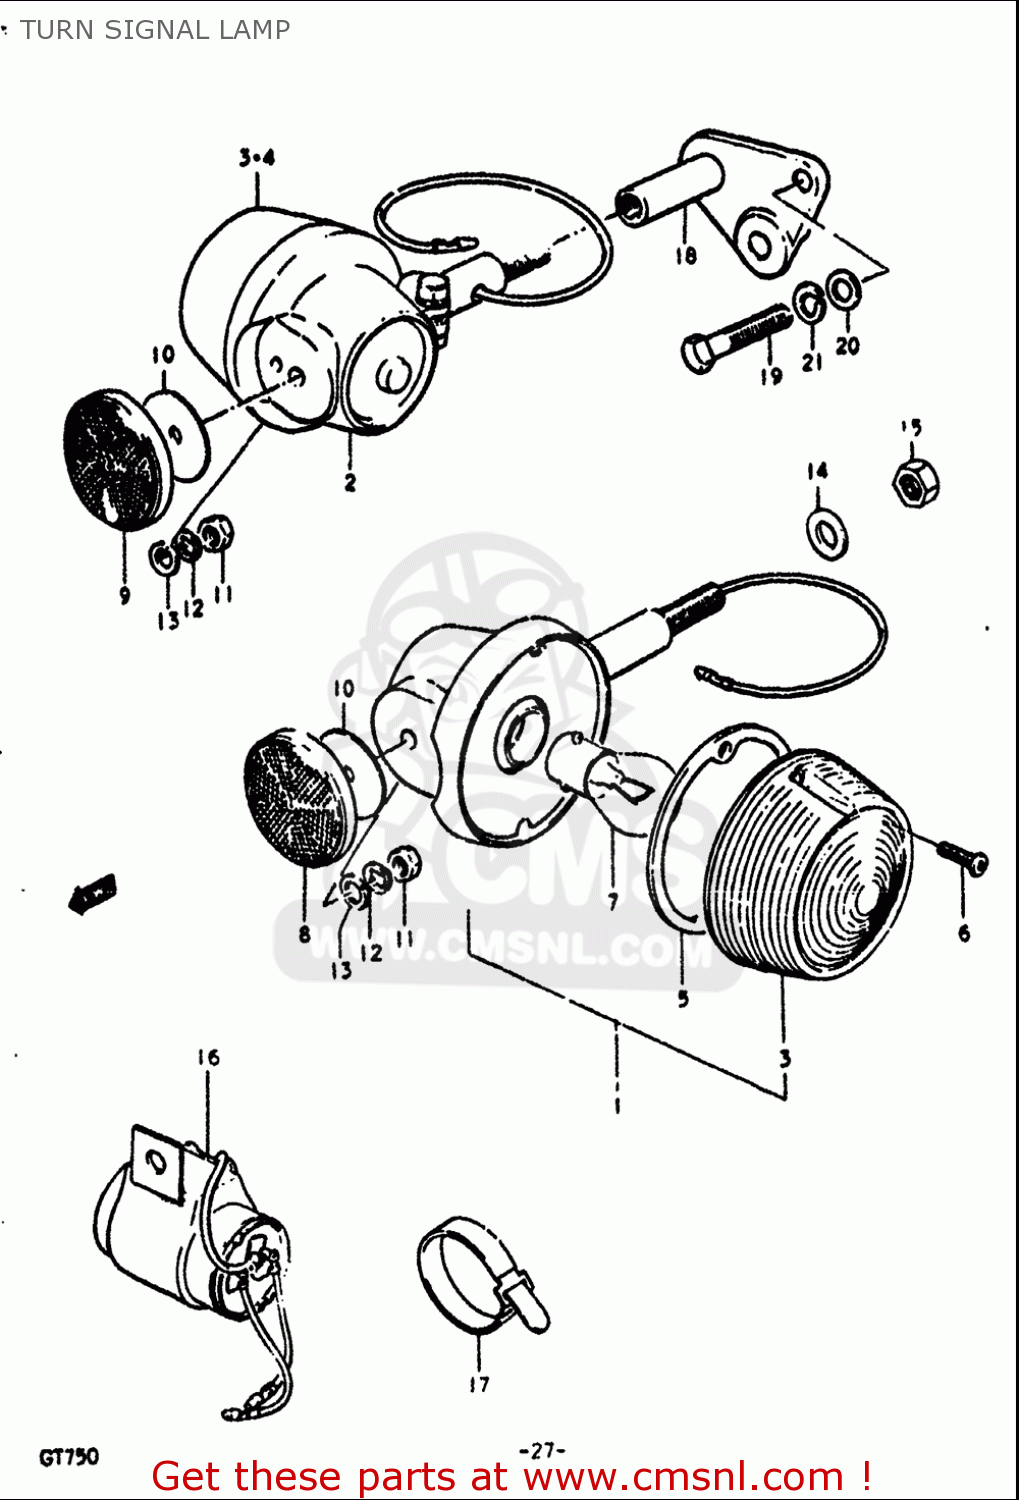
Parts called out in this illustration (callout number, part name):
3	LENS
5	GASKET,TURNSIGNAL LENS (NAS)
6	SCREW
7	BULB(12V23W,STANLEY,A4577A)
8	REFLEX REFLECTOR,RR
11	NUT
12	WASHER,LOCK
13	WASHER(5.5X18X1)
14	WASHER
15	NUT
16	RELAY,TURN SIGNAL
17	CLAMP
18	BRACKET, REAR TURN SIGNAL RH
19	BOLT
20	WASHER
21	WASHER,LOCK
